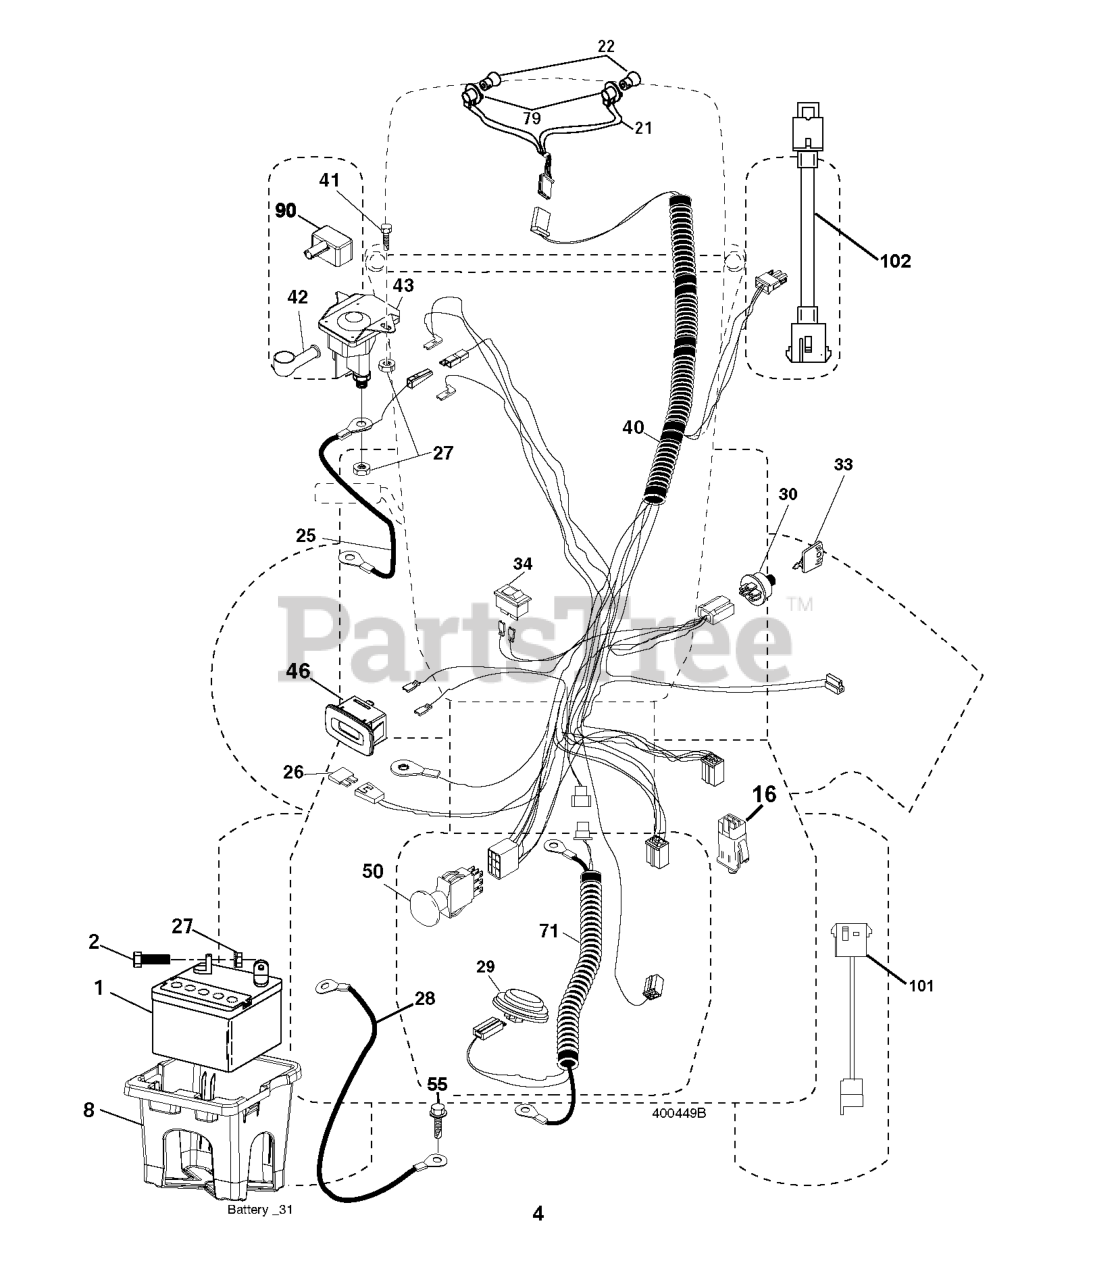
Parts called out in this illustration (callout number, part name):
1	BATTERY 12V .35 AMP
2	BOLT.HEX.1/4.X.3/4.DICHROMATE
8	BOX.BATTERY.MNT.REAR.L
16	SWITCH INTERLOOK PUSH-IN
21	HARNESS.LIGHT W/4152J BULBS
25	CABLE.STARTER.6GA.RED.
26	FUSE 20AMP
27	NUT
28	CABLE.BLACK.18"REAR.BA
29	SWITCH.SEAT.DELTA.OPC.
30	SWITCH.IGN.DELTA.W.LGH.ROS
33	KEY MLD GEN DELTA
40	HARNESS.IGN.DASH.HUQ/P
41	SCREW
42	TERMINAL COVER
43	SOLENOID.W/BRASS.PLUNGER
46	RP.GUAGE.SRVCMNDR.HRMTR.
50	RP.PTO.SWITCH.8 TERMINAL.BLACK
55	SCREW 5/16"
71	HARNESS.IGN.CHASS.TEX.REAR.BAT
79	BULB HOLDER ASM.
90	COVER, TERMINAL BATTERY
101	PIGTAIL.MATNLK.NEW.HAR
102	HARNESS PIGTAIL PCH TEX ROS
